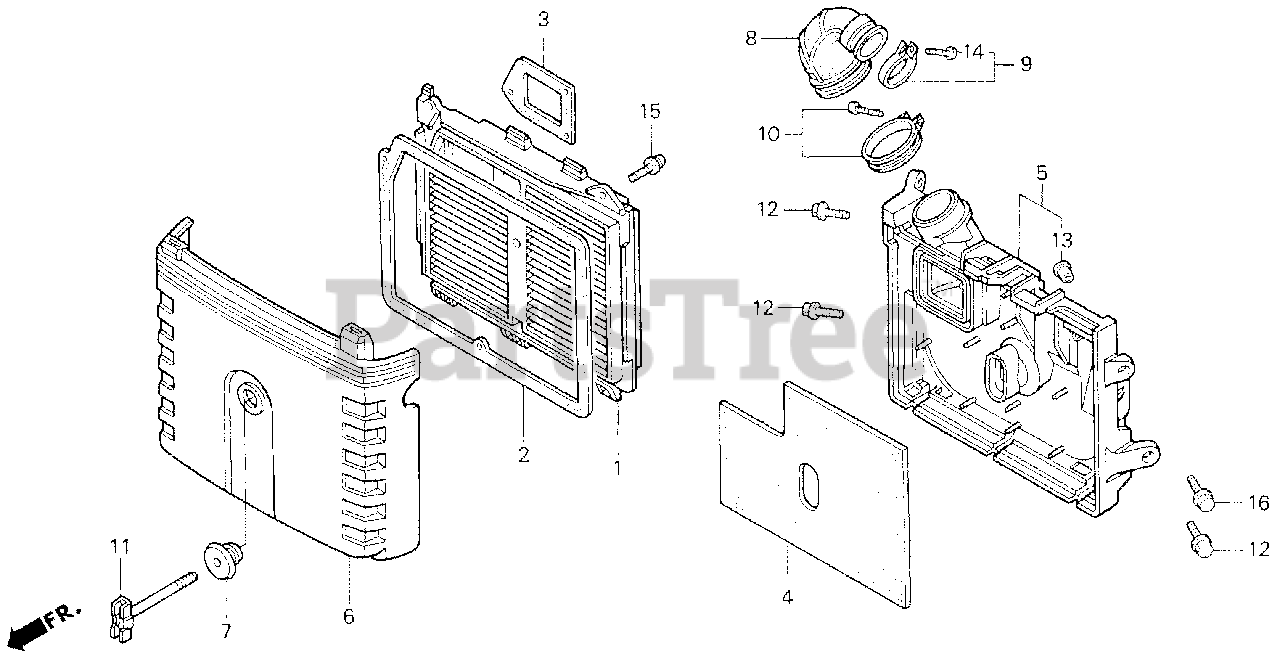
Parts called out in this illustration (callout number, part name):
1	ELEMENT SET, AIR CLEANER
1	ELEMENT, AIR CLEANER
2	GASKET A, ELEMENT
3	GASKET B, ELEMENT
4	FILTER (OUTER)
5	HOUSING, AIR CLEANER
6	COVER, AIR CLEANER
7	GROMMET, AIR CLEANER
8	TUBE, AIR CLEANER CONNECTING
9	BAND, AIR CLEANER CONNECTING TUBE
10	BAND B, AIR CLEANER
10	BAND, AIR CLEANER CONNECTING TUBE (50)
11	BOLT, AIR CLEANER
12	BOLT, FLANGE (6X23)
13	COLLAR, AIR CLEANER HOUSING
14	SCREW, PAN (4X20)
15	SCREW-WASHER (5X16)
16	BOLT, FLANGE (6X18)
